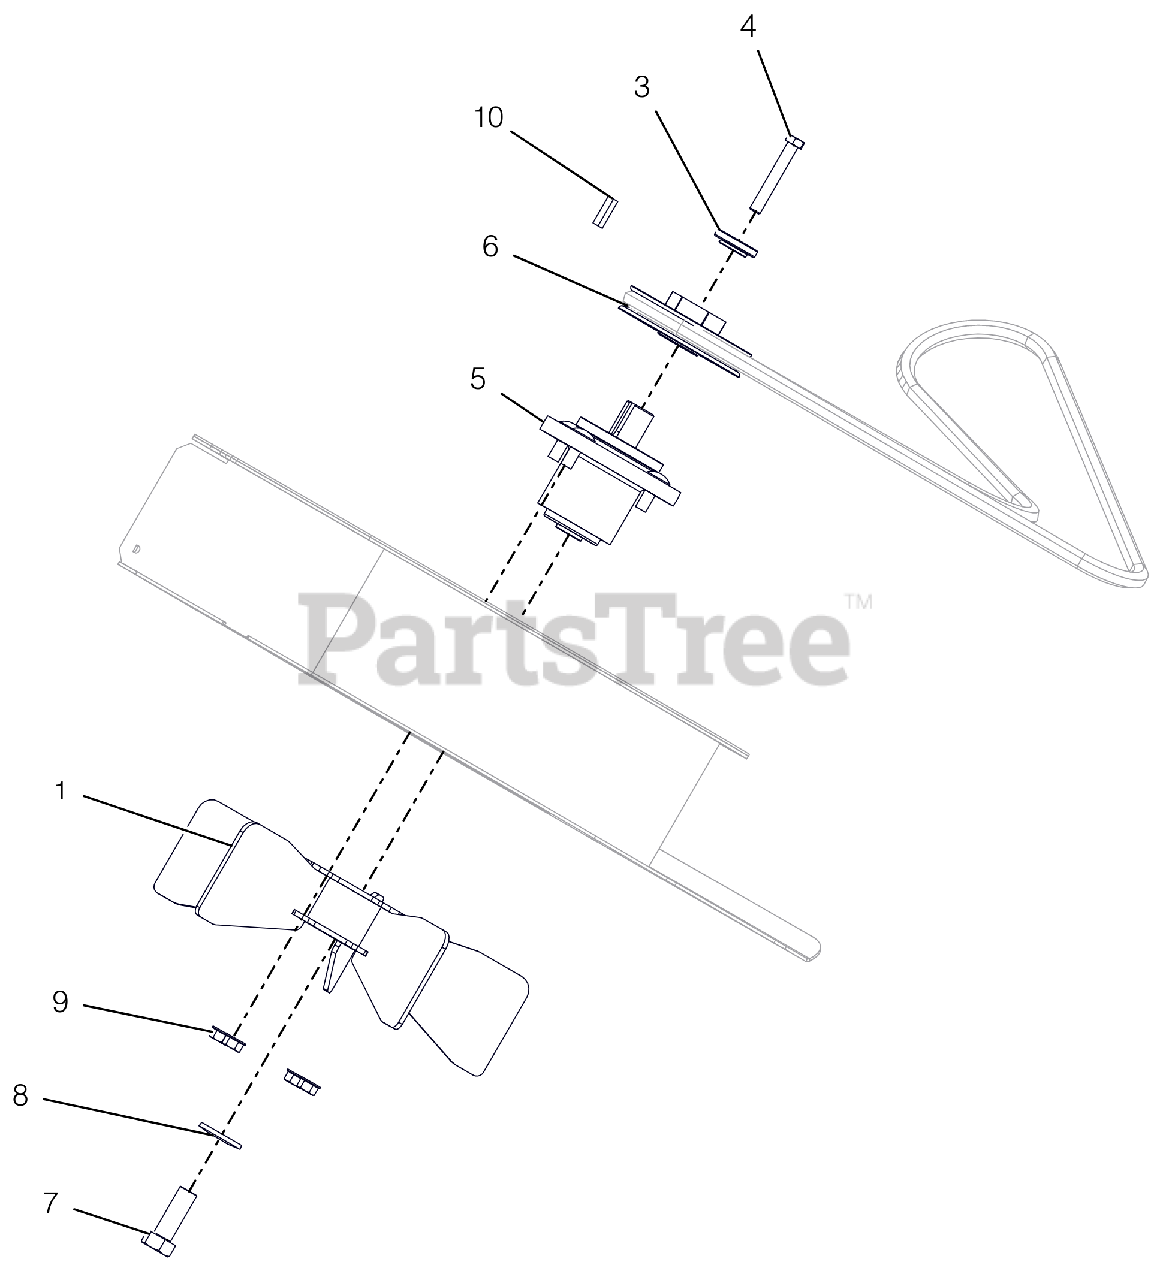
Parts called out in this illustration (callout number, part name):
1	IMPELLER, HD BLOWER
3	RETAINER, SHEAVE
4	BLT-HEX .38-16X2.50 GR8 YWZC
5	SPINDLE ASSY, SERVICE (BLOWER)
6	PULLEY, V-1.00"ID X 4.50" OD
7	BLT-HEX .62-18X1.75 GR8 YWZC
8	WSHR-BLVL .669X1.535X.138
9	@NUT-LK-TOP-FLG .38-16 YWZC
10	KEY, SQ .25X.25X1.00 RC 40-50
